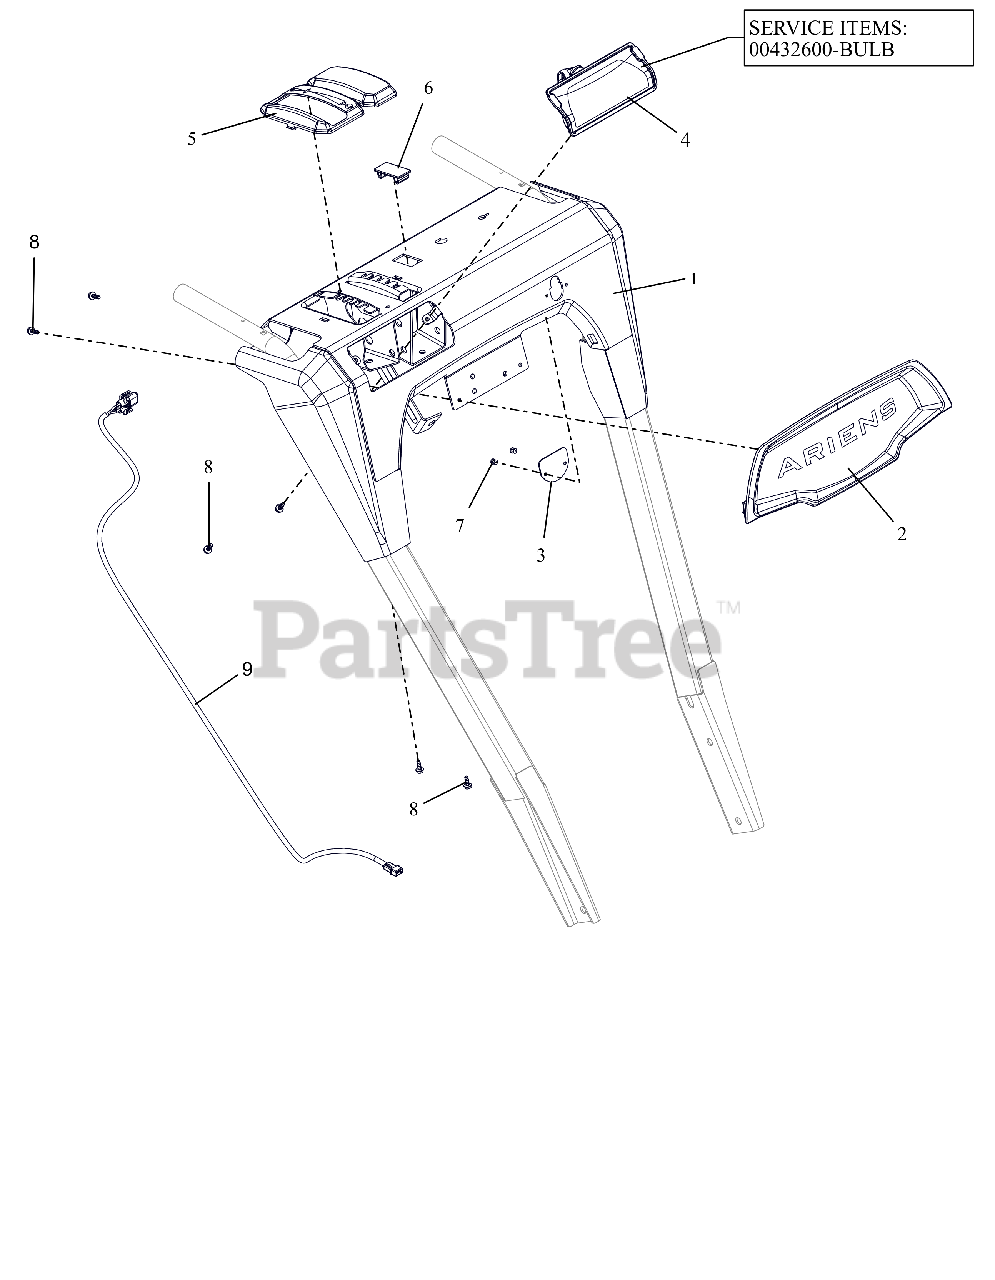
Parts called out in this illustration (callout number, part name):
1	PANEL, DASH - W/CTR DECAL
2	BEZEL, DASH - ARIENS LG DASH
3	COVER, DASH BRKT, BRUSH
4	HEADLIGHT ASY, HALO 20W 2SHOT
4	BULB, LIGHT-HALOGEN 20W
5	BEZEL, SHIFT - FRICTION BRUSH
6	PLUG,DASH PANEL
7	RVT-POP #43 .125X.313 STL ZINC
8	SCR-TAP #10X.50 BOSS INDHXHD
9	HARNESS, LIGHT - DELUXE
